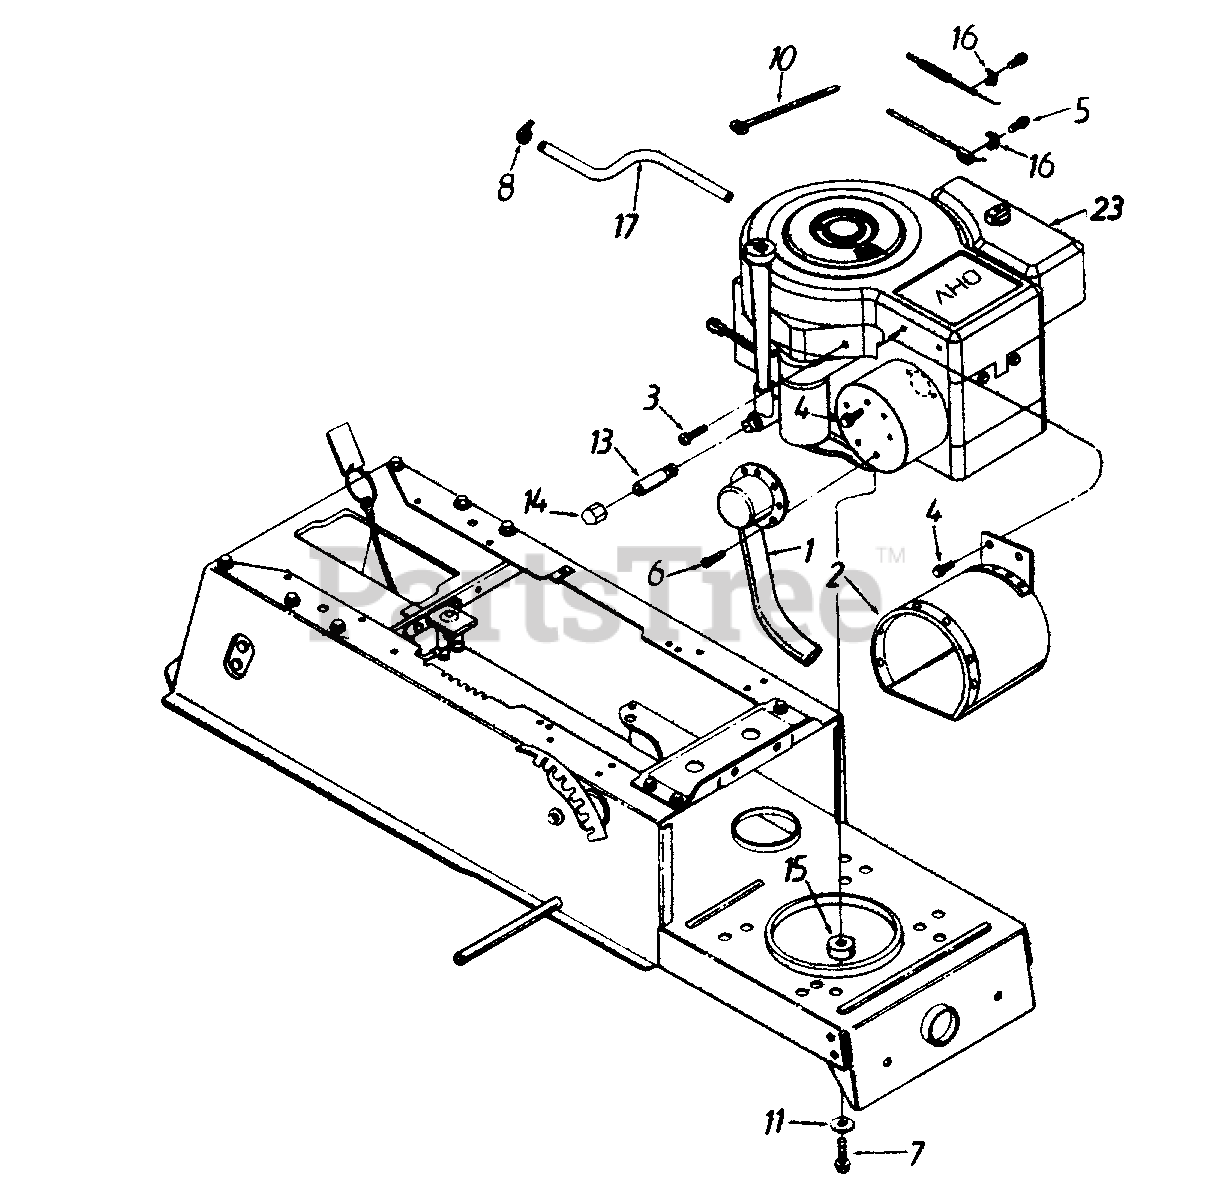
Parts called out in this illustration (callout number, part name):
1	Exhaust Pipe Ass'y.
2	Heat Shield Ass'y.
3	Pan Hd. Mach. Scr. 5/16-18 x .75"
4	Hex Wash. Hd. Scr. 1/4-20 x .5"
5	Hex Slot Wash. Hd. #10-32 x 5/8" Lg.
6	Hex Wash. Hd. F-Tap Scr. #8-32 x .38"
7	Hex L-Wash. TT-Tap Scr. 3/8-16 x 1.5"
8	House Clamp - .49" Dia.
10	Cable Tie - 4" I.D.
11	Flat Wash. 3/8" I.D. x 1.25" O.D.
13	Pipe Nipple 3/8-18 NPT x 2" Lg.
14	Cap - Oil Drain
16	Casing Clamp
17	Fuel Line Hose
23	Engine
